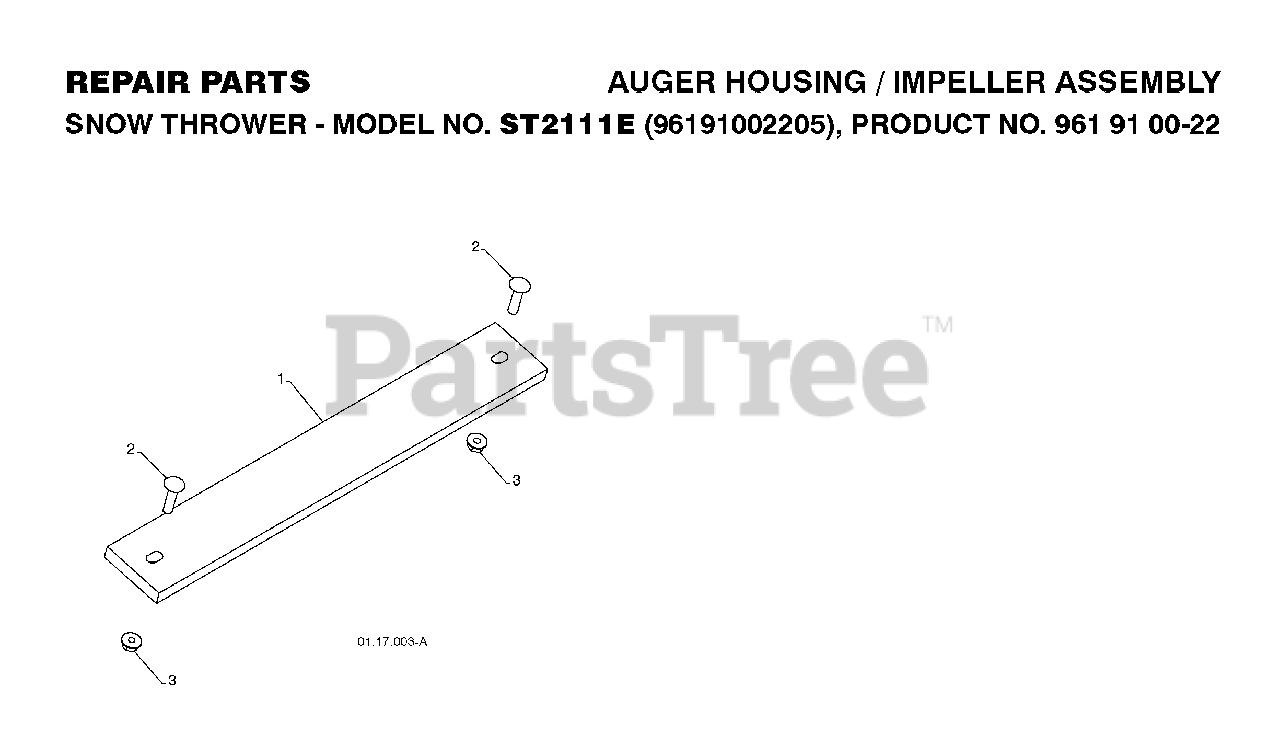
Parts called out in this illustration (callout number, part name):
1	WEIGHT AUGER HOUSING 30
2	BOLT.CARRIAGE.5/16-18
3	NUT, LOCK 5/16-18
